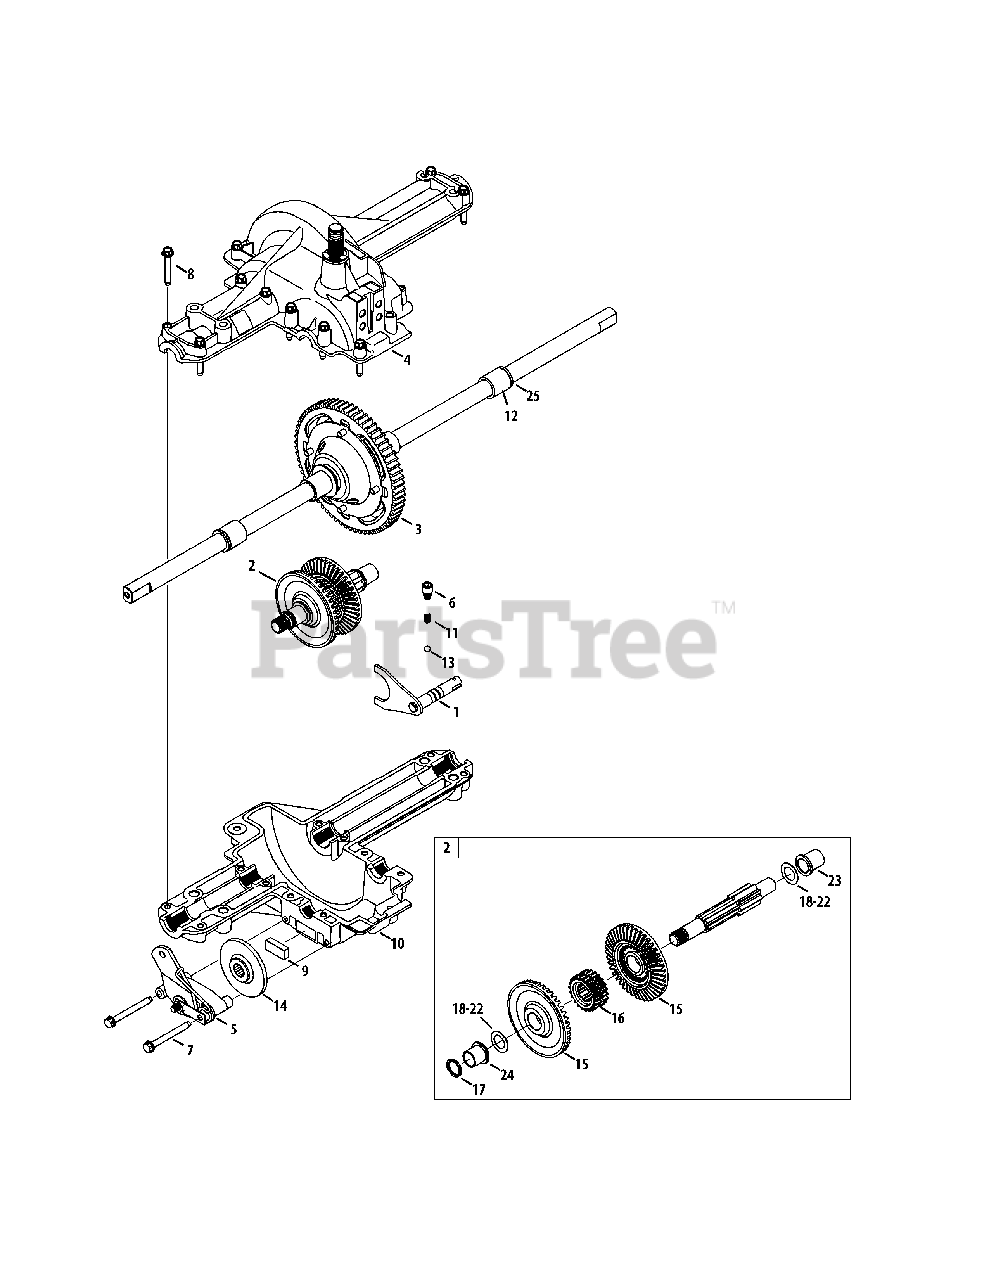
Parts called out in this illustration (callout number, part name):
1	Shaft Ass’y, Detent
2	Shaft Ass’y, Drive, Fwd-Rev
3	Differential Ass’y
4	Housing Ass’y, Upper
5	Brake Ass’y, Yoke, RH
6	Shcs, Self-tapping, 5/16-18, .375
7	Screw, Self-tapping, 1/4-20, 2.375,
8	Screw, Self-tapping, 1/4-20, 1.625,
9	Pad, Brake
10	Housing, Lower
11	Compression Spring
12	Bearing, Sleeve, .75 x 1.00 x .42
13	Ball, Detent, .250
14	Disc, Brake
15	Gear, Bevel, 42t, Spline
16	Collar, Clutch
17	Seal, .625 x .812 x .094
18	Washer, Flat, 5/8x1.00x.030 Hd
19	Washer, Flat, .634x1.00x.04,
20	Washer, Flat, .63 x 1.00 x .02
21	Washer, Flat, .632x1.00x.035
22	Washer, Thrust, 1.00 x .632 x .0
23	Bearing, Flange, 5/8 x 3/4 x 3/4
24	Bearing, Flange, 5/8 x 3/4 x 15/16
25	Seal, .75 x 1.00 x .125
